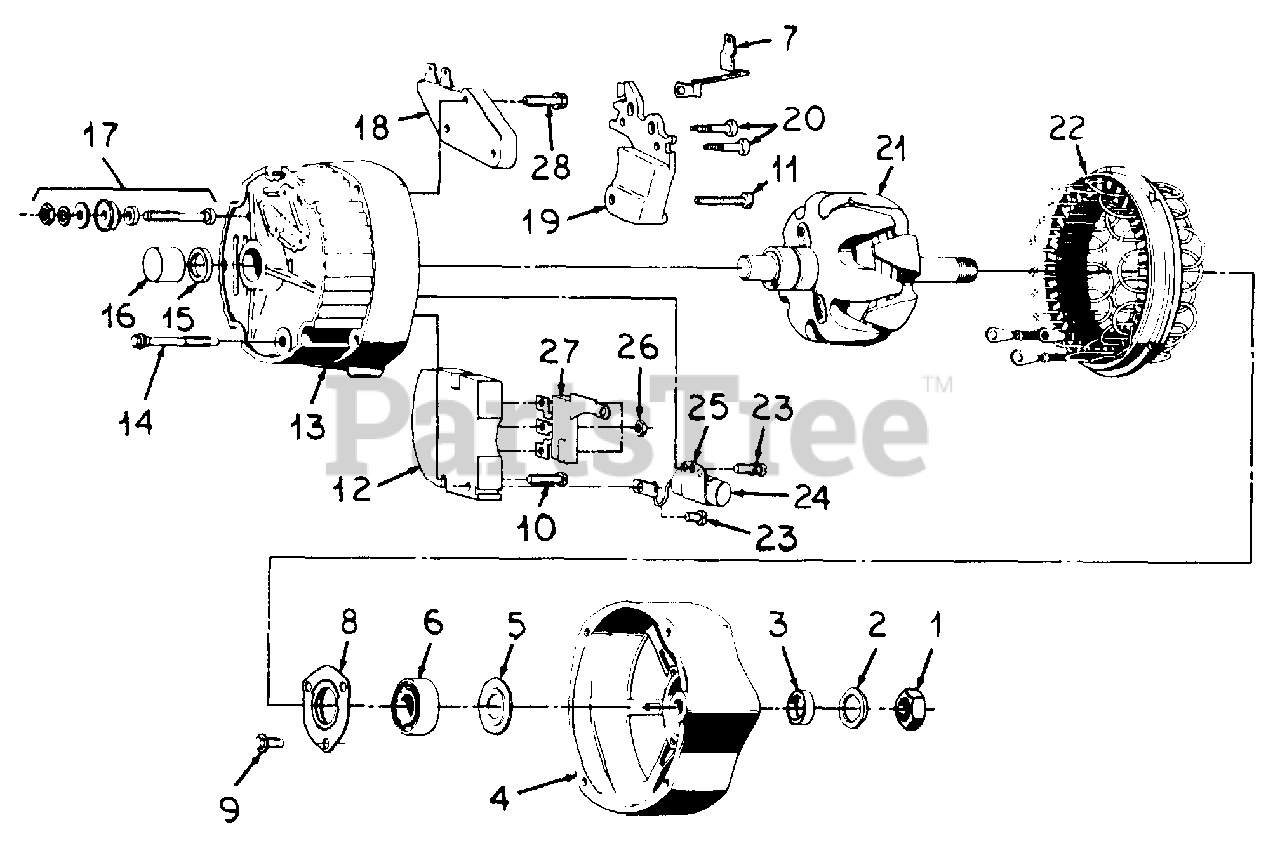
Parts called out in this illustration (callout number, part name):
1	NUT, DRIVE SHAFT END
2	WASHER, DRIVE END SHAFT LOCK
3	COLLAR, DRIVE END SHAFT -OUTSIDE-7/8 IN. OD
4	PACKAGE, DRIVE END FRAME
5	WASHER, DRIVE END GREASE SLINGER
6	BEARING, DRIVE END BALL
7	TERMINAL, RELAY
8	PLATE, DRIVE END BALL BEARING RETAINER
9	SCREW, BEARING RETAINER PLATE ATTACHING
10	SCREW, RECTIFIER SUPPORT
11	SCREW, BRUSH HOLDER PIVOT
12	SUPPORT, RECTIFIER
13	PACKAGE, SLIP RING END FRAME
14	SCREW, FRAME ATTACHING
15	SEAL, SLIP RING END ROLLER BEARING
16	BEARING, SLIP RING END ROLLER
17	PACKAGE, BATTERY OUTPUT TERMINAL
18	REGULATOR, VOLTAGE
19	HOLDER ASSY, BRUSH AND BRUSH
20	SCREW ASSY, BRUSH HOLDER INSULATED
22	STATOR ASSY
23	SCREW W/LOCK WASHER CAPACITOR BRACKET AND LEAD ATTACHING
24	CAPACITOR ASSY
25	BRACKET, CAPACITOR MOUNTING
26	NUT, NO. 8 CDP HEX. MACH SCREW TYPE 1
27	RECTIFIER, DIODE TRIO
28	SCREW ASSY, BRUSH HOLDER GROUND
